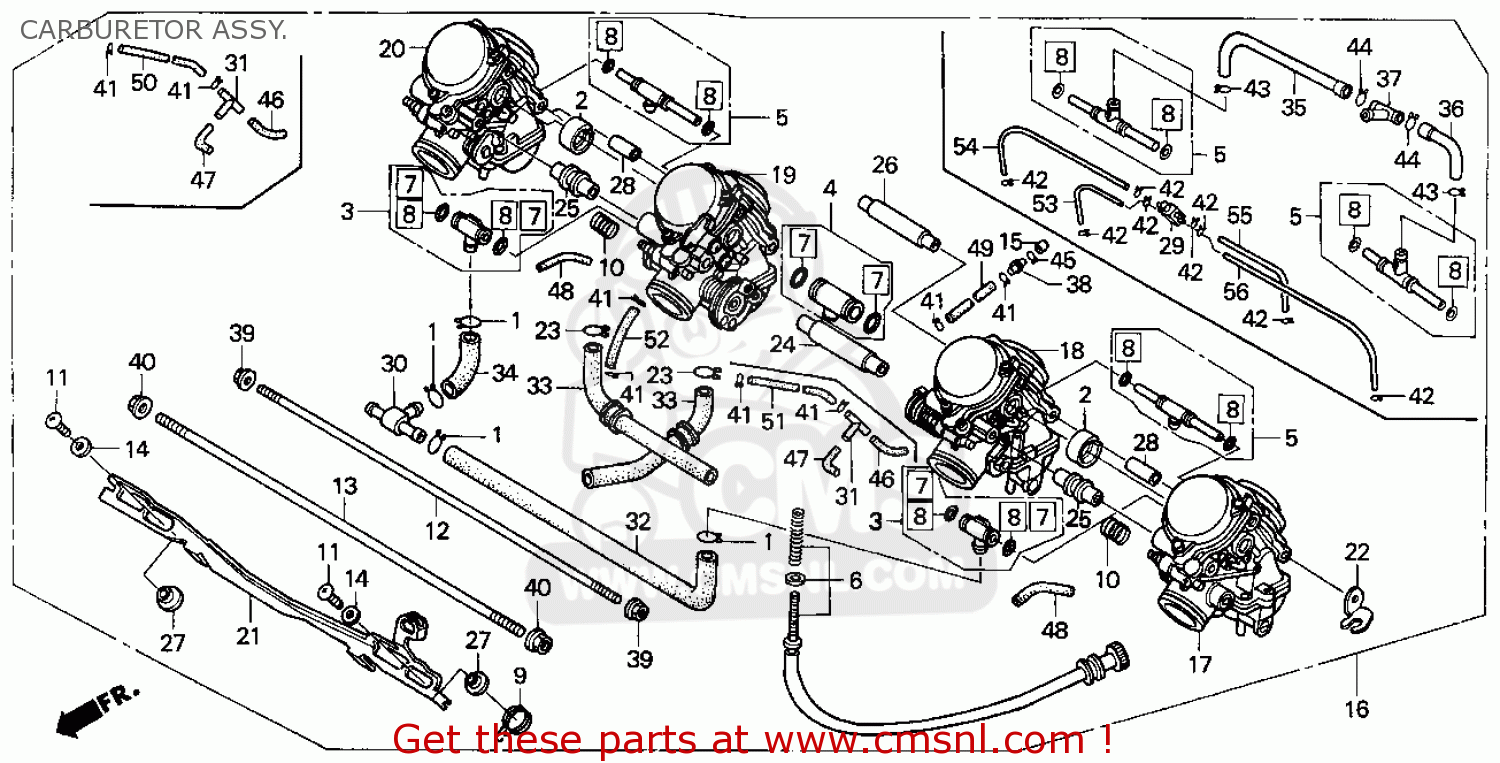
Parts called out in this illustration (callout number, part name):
1	CLIP,BRTHR TUBE
2	JOINT
3	JOINT SET
4	JOINT SET
5	JOINT SET
6	SCREW SET
7	GASKET SET C
8	GASKET SET B
9	TORS COIL SPG.
10	SPRING
11	WASHER,SCREW
12	BOLT
13	BOLT
14	WASHER,PLAIN
15	CAP
16	CARBURETOR (VP83D A)
17	CARBURETOR ASSY. 1
18	CARBURETOR ASSY. 2
19	CARBURETOR ASSY. 3
20	CARBURETOR ASSY. 4
21	LEVER,STARTER
22	PLATE,STAY
23	TUBE,CLIP
24	COLLAR
25	COLLAR
26	COLLAR
27	COLLAR
28	DOWEL PIN
29	JOINT (T)
30	T-JOINT
31	JOINT,T TYPE
32	TUBE
33	TUBE COMP
34	TUBE
35	TUBE
36	TUBE
37	JOINT,THREEWAY (A
38	JOINT, 2WAY, 3.5
39	NUT,FLANGE,5MM
41	CLIP B1 7,TUBE
42	CLIP B1 8,TUBE
43	CLIP B1 12,TUBE
44	CLIP B1 12.5,TUBE
45	CLIP B1 6.5 TUBE
46	BULK TUBE,TB 35X1
47	BULK TUBE,TB 35X1
48	BULK TUBE,TB 35X1
49	BULK TUBE,TB 35X1
50	BULK TUBE,TB 35X1
51	BULK TUBE,TB 35X1
52	BULK TUBE,TA 35X8
53	BULK TUBE,TB 45X1
54	BULK TUBE,TB 45X1
55	BULK TUBE,TB 45X1
56	BULK TUBE,TB 45X1
